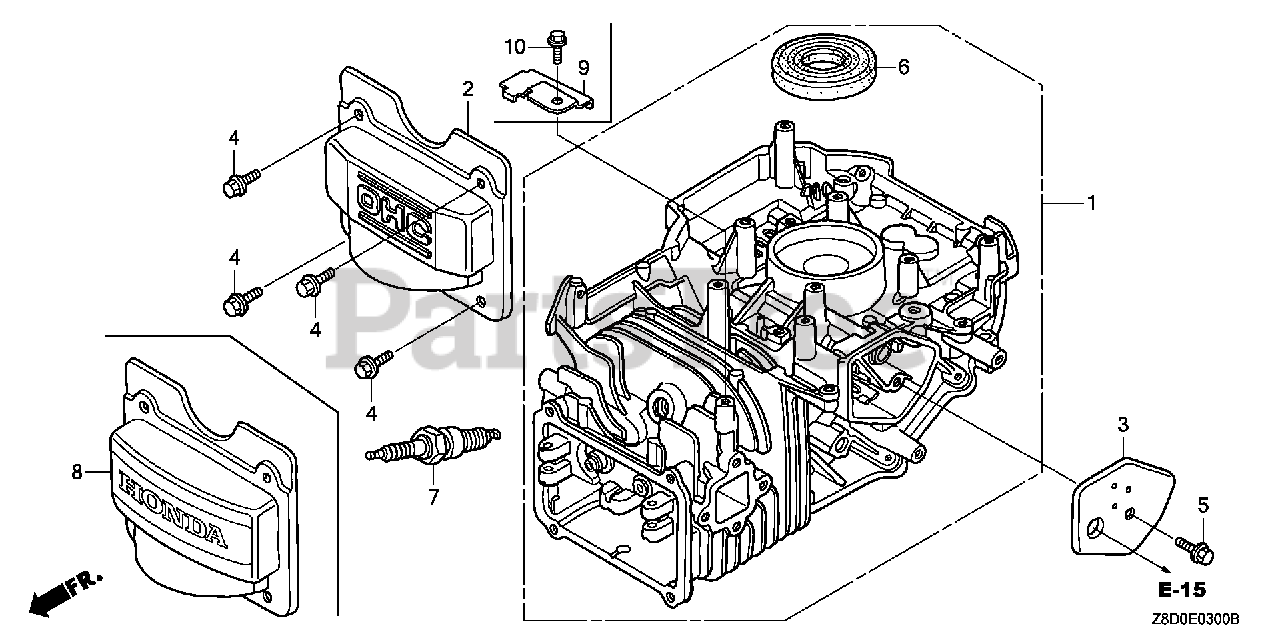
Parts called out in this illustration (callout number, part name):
1	CYLINDER ASSY.
3	COVER, BREATHER (Honda Code 5580006). (BREATHER VALVE ASSY.)
4	BOLT, FLANGE (6X12) (CT200)
5	BOLT, FLANGE (6X14)
6	OIL SEAL (25.4X62X6)
7	SPARK PLUG (BPR5ES) (NGK)
8	COVER, HEAD
